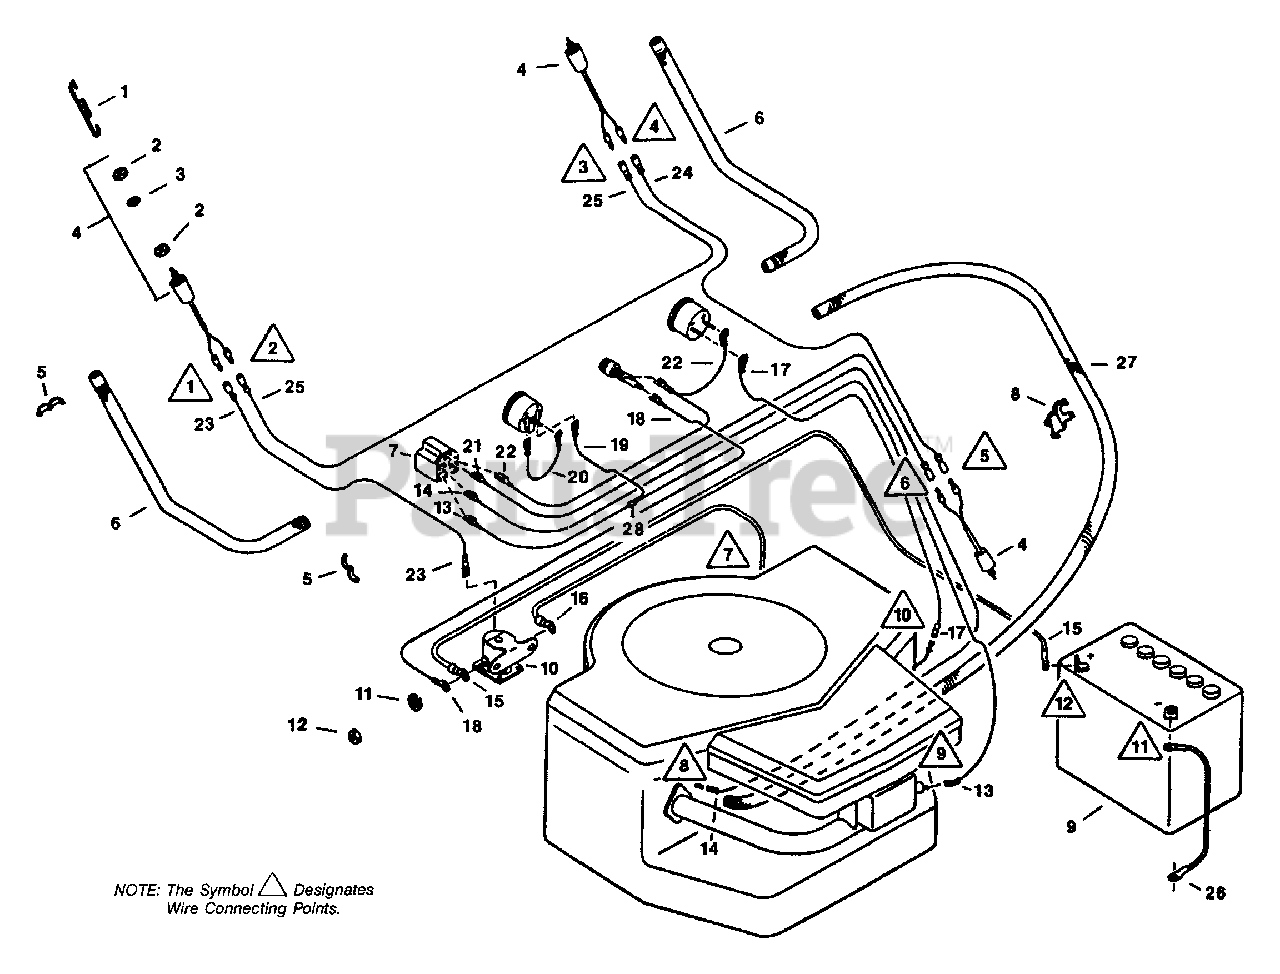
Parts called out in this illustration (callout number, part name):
1	Spring
2	M10 x .75 Hex Nut
3	Vinyl Washer
4	Interlock Switch-Complete
5	Flex Guard Clip
6	Flex Guard Loom
7	5 Terminal Connector
8	Flex Guard Outlet
9	12 Volt Battery
10	SOLENOID
11	5/16" Lock Washer
12	5/16"-18 Regular Hex Nut
13	After Fire Wire
14	Engine Kill Wire
15	Solenoid-Battery (Pos.) Cable
16	Solenoid-Starter Cable
17	D.C. Wire
18	Fuse-Solenoid Wire
19	Hour Meter (Pos.) Wire
20	Hour Meter Ground Wire
21	L.L. Intlk.-"S" Term. Wire
22	Fuse - "B" Term. - Amp (Pos.) Wire
23	U.R. Intlk.-Sol. Starter Term. Wire
24	U.L.-L.L. Intlk. Wire
25	U.R.-U.L. Intlk. Wire
26	Battery (Neg.) Cable
27	Flex Guard Loom
28	Quick Splice
